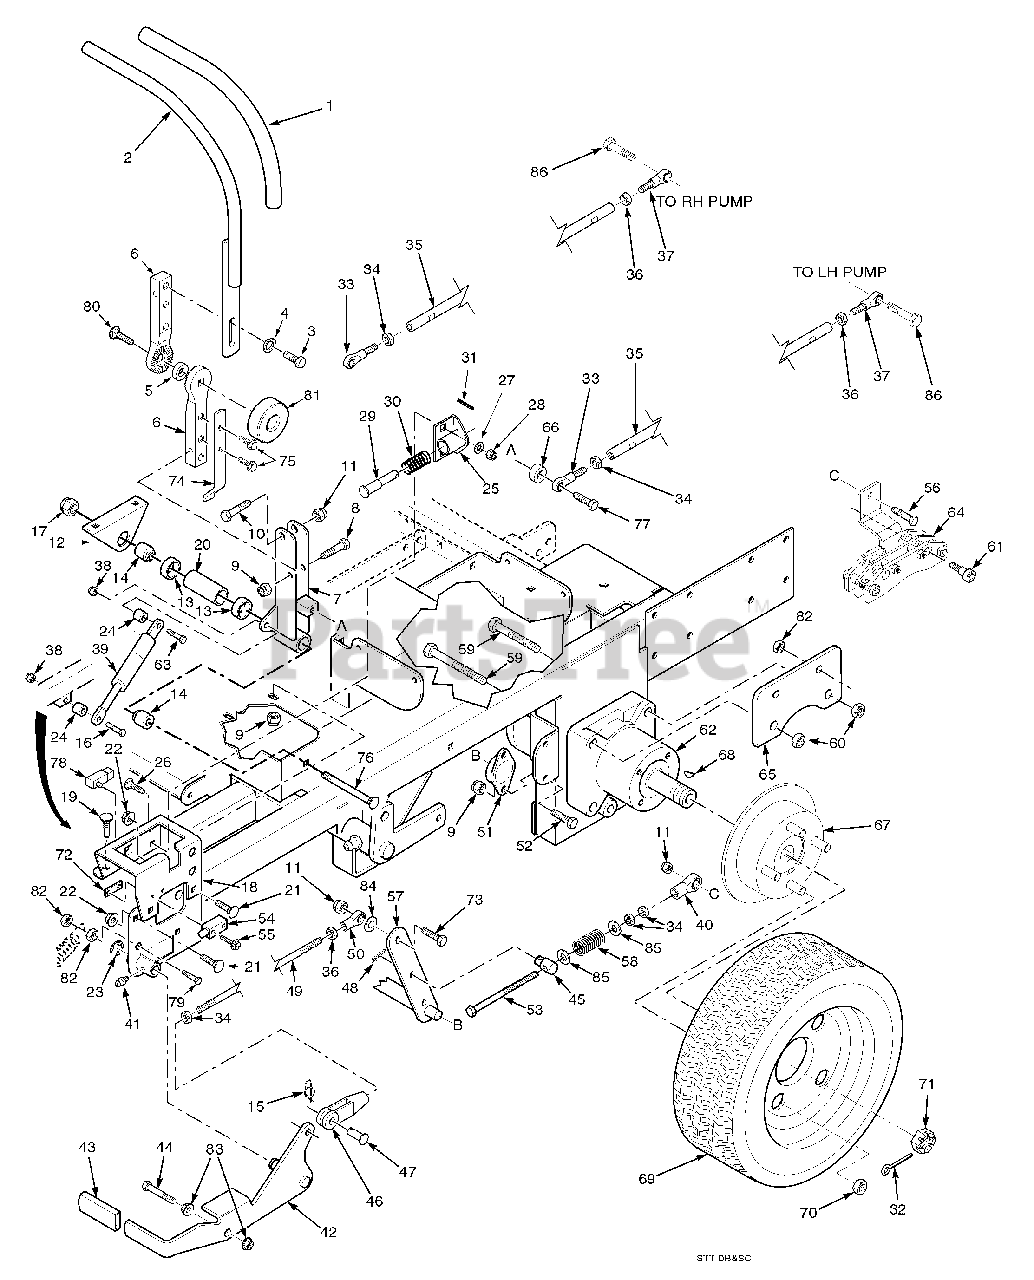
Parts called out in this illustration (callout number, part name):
1	Grip, Handle Bar
2	Handle Bar, LH
3	Bolt, Hex Head 5/16-18 x 1”
4	Lockwasher, 5/16”
5	Rubber Spacer
6	Bar, Control Lever
7	Control Lever Weldment, LH
8	Bolt, Hex Head 5/16-18 x 2”
9	Nut, Hex Elastic Stop 5/16-18
10	Bolt, Hex Head 3/8-16 x 2”
11	Nut, Hex Elastic Stop 3/8-16
12	Mount, Control Linkage
13	Ball Bearings, Neutral Return
14	Spacer
15	Pin, Rue Cotter 3/8 Dia.
16	Bolt, Hex Head, 5/16-18 x 2.75 Zinc
17	Nut, Hex Elastic Stop 5/8-11
18	Bracket, Control Lever LH
19	Bolt, Carriage 5/16-18 x 1”
20	Spacer, Bearing
21	Bolt, Carriage 5/16-18 x 3/4”
22	Nut, Hex Serrated Flange 5/16-18
23	Ring, Retaining 5/8” External “E”
24	Spacer
25	Bracket, Neutral Return
26	Bolt, Carriage 1/4-20 x 3/4”
27	Flatwasher, 1/4”
28	Nut, Hex Elastic Stop 1/4-20
29	Pin, Retaining Spring
30	Spring
31	Roll Pin, Spring 5/32 x 3/4”
32	Pin, Cotter 9/16 x 1-1/2”
33	Rod End, Male 3/8-24 RH Thread
34	Nut, 3/8-24 RH Thread
35	Tube, Control Link
36	Nut, Hex 3/8-24 LH Thread
37	Rod End, Male 3/8-24 LH Thread
38	Locknut, 5/16-18, Elastic Stop
39	Gas Damper
40	Rod End, 3/8-24 RH Female
41	Grease Fitting
42	Lever, Parking Brake
43	Grip, Parking Brake
44	Bolt, Hex Head 3/8-16 x 2-3/4”
45	Swivel Joint
46	Clevis, Traction Control
47	Pin, Clevis
48	Hair Pin Cotter
49	Rod, Parking Brake
50	Rod End, LH Thread
51	Bushing, Self Align
52	Bolt, Hex Head 5/16-18 x 3/4”
53	Bolt, Hex Hd 3/8-24 x 5-1/2”
54	Switch, Parking Brake
55	Screw, Hex Slotted Washer Head #10 32 x 3/4”
56	Bolt, Hex Head 3/8-16 x 1-1/4”
57	Bellcrank, Brake Actuator
58	Spring
59	Bolt, Hex Hd 1/2-13 x 2-3/4”
60	Locknut, Hex 1/2-13 Center Lock
61	Bolt, Shoulder 1/2 x 3/8-16 x 2-3/4”
62	Wheel Motor, Hydro-Gear 18E
63	Bolt, Hex Head, 5/16-18 x 1.75, Zinc
64	Brake Caliper
65	Mounting Bracket, Brake
66	Spacer
67	Wheel Hub/Disk Brake Assembly
68	Key, Woodruff 5/16 x 1”
69	Wheel Assembly 24 x 12-12 Turf Master
70	Lug Nut, 1/2-20
71	Nut, Hex Castle
72	Threaded Plate
73	Bolt, Hex Head 3/8-16 x 1-1/2”
74	Actuator, Switch
75	Bolt, Hex Serrtd Flng 5/16-18 x 3/4”
76	Bolt, Hex Head 5/8-11 x 4-1/2”
77	Bolt, Hex Head 3/8-16 x 1-1/4”
78	Switch, Handle Neutral
79	Bolt, Hex Head 3/8-16 x 1-1/4” Grd 8
80	Bolt, Carriage 3/8-16 x 1-1/2”
82	Nut, Center Lock 3/8-16
83	Nut, Serrated Flange 3/8-16
84	Flatwasher, 3/8-.391 x .938 x .105
85	Flatwasher, 3/8-.406 x .812 x .065
86	Bolt, Hex Head, 3/8-16 x 1-3/4”
